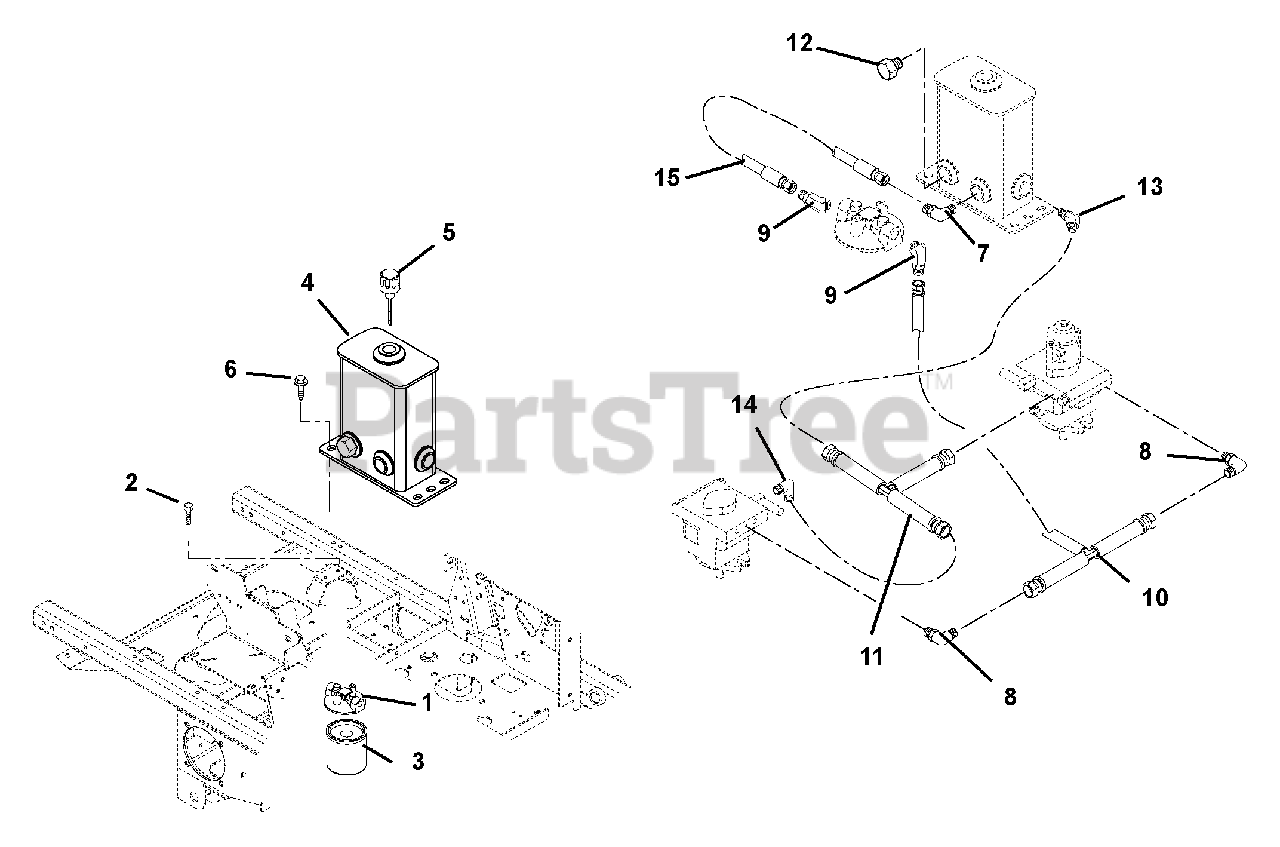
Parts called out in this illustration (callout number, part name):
1	Head, Filter
2	Bolt, Hex .25-20 x .50 Epoxy Grade 5
3	Oil Filter
4	Weldment, Hydraulic Tank
5	Dipstick, Breather
6	Screw, Tapping .38-16 x .75 Hex Washer Head
7	Fitting, Hydraulic, 90 Degree Elbow, Steel M8F-M80
8	Fitting, Elbow M6O-M8F
9	Fitting, Hydraulic 45° M80-M120
10	Hose, Tee Assembly, .50
11	Hose, .38 Tee Assembly
12	Plug, Hex, .75-16 O-Ring
13	Fitting, Hydraulic 45 Degree M6F-M8O
14	Fitting, Hydraulic (6 C5OLO)
15	Hose, Hydraulic
